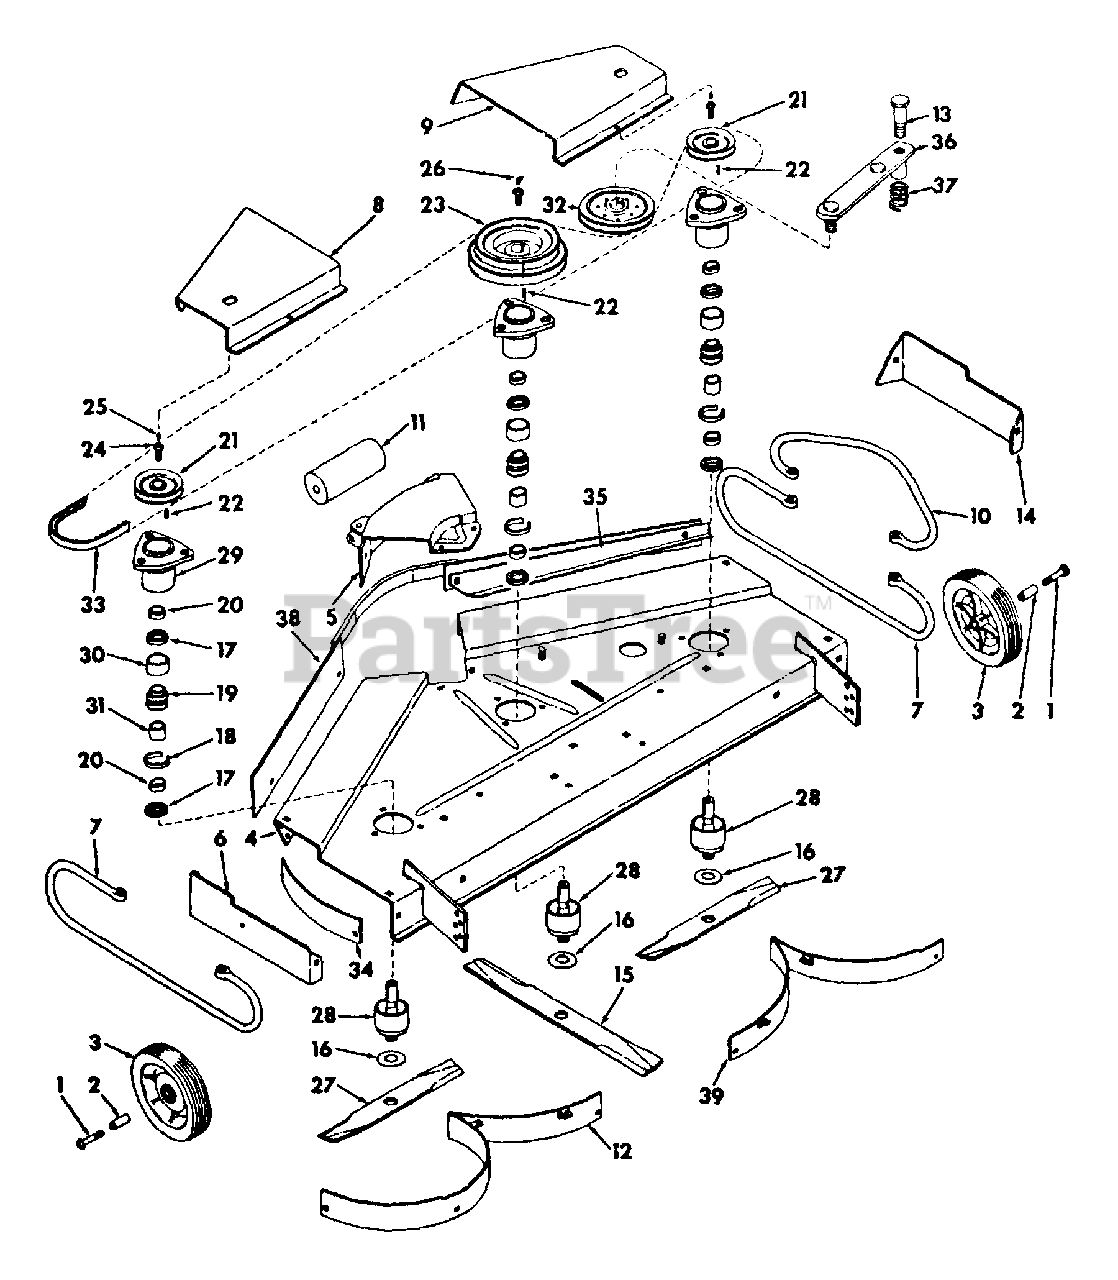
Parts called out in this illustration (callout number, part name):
1	BOLT, SHOULDER
2	BUSHING, WHEEL
3	WHEEL, 7 IN. GAUGE
4	HOUSING ASSY, ROTOR
5	HOUSING, CENTER
6	SIDE, HOUSING LH
8	SHIELD, BELT LH
9	SHIELD, BELT RH
10	GUARD, DISCHARGE
11	ROLLER, FRONT
12	SHROUD ASSY, LH
13	BOLT, IDLER ARM PIVOT
14	MULCHER PARTS ACCESSORY
15	BLADE, CENTER
16	WASHER, BLADE FRICTION
17	SEAL, SPINDLE OIL
18	SPACER, SPLIT OUTER
19	BEARING ASSY, SPINDLE
20	SPACER, PULLEY
21	PULLEY, OUTER
22	KEY, 1/4 x 3/4 x SQ. PARALLEL
23	PULLEY, CENTER
25	FITTING, 5/16 DRIVE TYPE STR LUB
26	FITTING, 3/8 x 45 DEG ANGLE LUB
27	BLADE, OUTER
28	DISK AND SPINDLE ASSY, BLADE DRIVE
29	HOUSING, SPINDLE
30	BUSHING, BRG SEPARATOR - OUTER
31	BUSHING, BRG SEPARATOR - INNER
32	PULLEY, FLAT IDLER
33	BELT, SPINDLE DRIVE
34	SHROUD, FRONT LH
35	BAFFLE, FRONT GRASS
36	ARM ASSY, IDLER
37	SPRING, TORSION
38	BAFFLE ASSY, MOWER FRONT
39	SHROUD ASSY, RH BLADE
18626-R1	BOLT, 1/4 x 1/2 C-Z SQ-NK CRG
18685-R1	BOLT, 3/8 x 1-1/2 C-Z SQ-NK CRG
18685-R1	BOLT, 3/8-16 x 1-1/2 C-Z SQ-NK CRG
20914-R1	BOLT, 1/2 x 7-1/2 C-Z SQ-NK CRG
180020	SCREW, 1/4-20 x 3/4 C-Z HEX-HD CAP
180123	SCREW, 3/8-16 x 1-1/8 C-Z HEX-HD CAP
